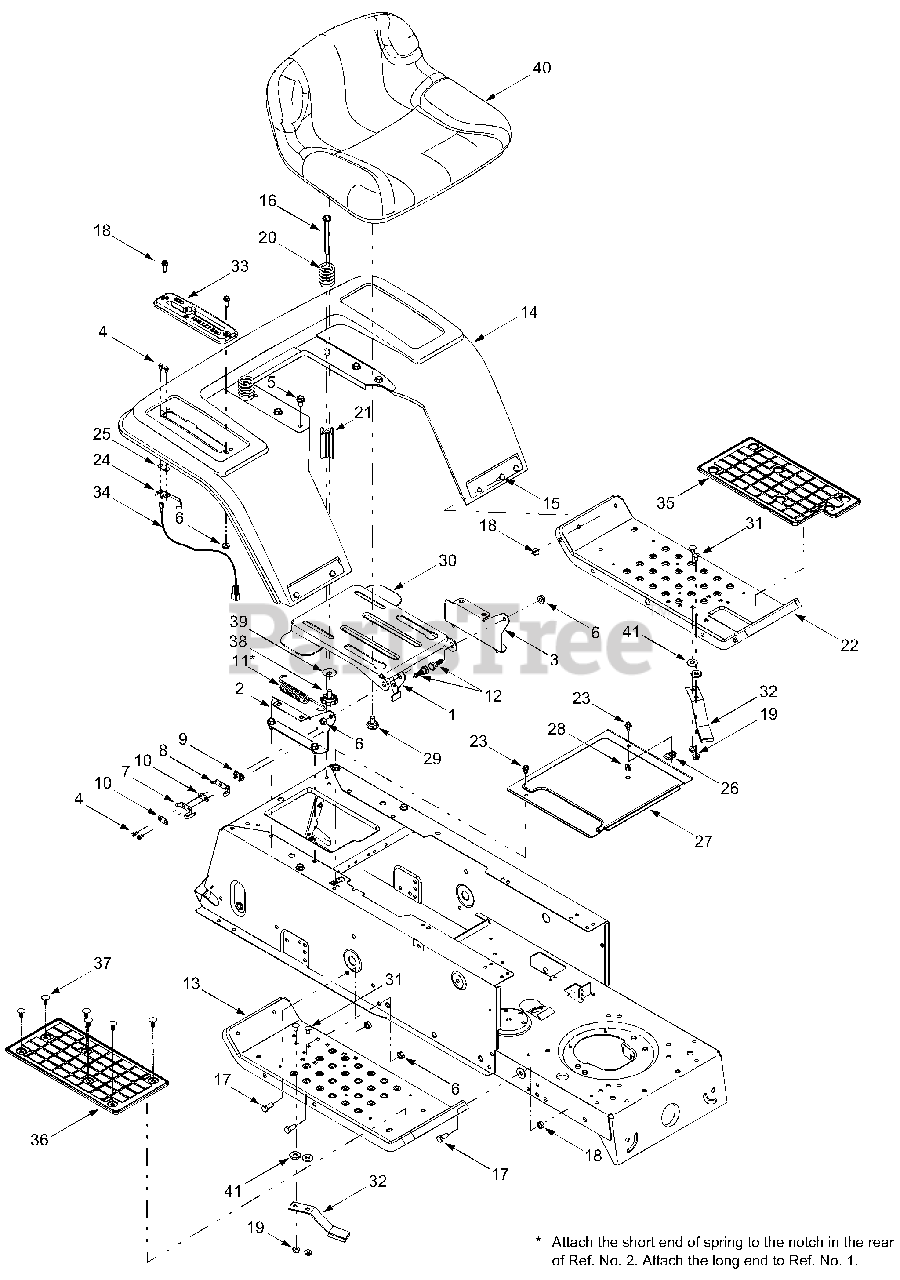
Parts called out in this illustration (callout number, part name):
1	Seat Lift Bracket
4	Self-tapping Screw, #8-18 x .50
5	Self-tapping Screw, 5/16-12 x .75
6	Lock Nut, 5/16-18
7	Outer Seat Spring Switch
8	Inner Seat Spring Switch
9	Insulator Plate Boss
10	Insulator Plate
11	Extension Spring, .75 x 5.31
12	Shoulder Screw, .437 x .286
16	Self-tapping Screw, 5/16-18 x 3.5
17	Hex Screw, 5/16-18 x .75
18	Self-tapping Screw, 1/4-20 x .75
19	Lock Nut, 1/4-20
20	Compression Spring, 1.314 x 1.8
21	Spacer
24	Spring Switch, Long
25	Insulator Nut Plate
26	U-Clip Nut, 1/4-20
29	Shoulder Screw, .625 x .175, 3/8-16
31	Carriage Screw, 1/4-20 x .50
32	Blade Spindle Brake Assembly
33	Speed Index Bracket
34	Wire Extension, Reverse
35	LH Rubber Foot Pad
36	RH Rubber Foot Pad
37	Ratchet Clip, .250 Dia
38	Knob, 3/8-16 x .625
39	Bell Washer, .389 x 1.120 x .030
40	Medium Back Seat, Yellow
41	Flat Washer, .344 x .750 x .120
